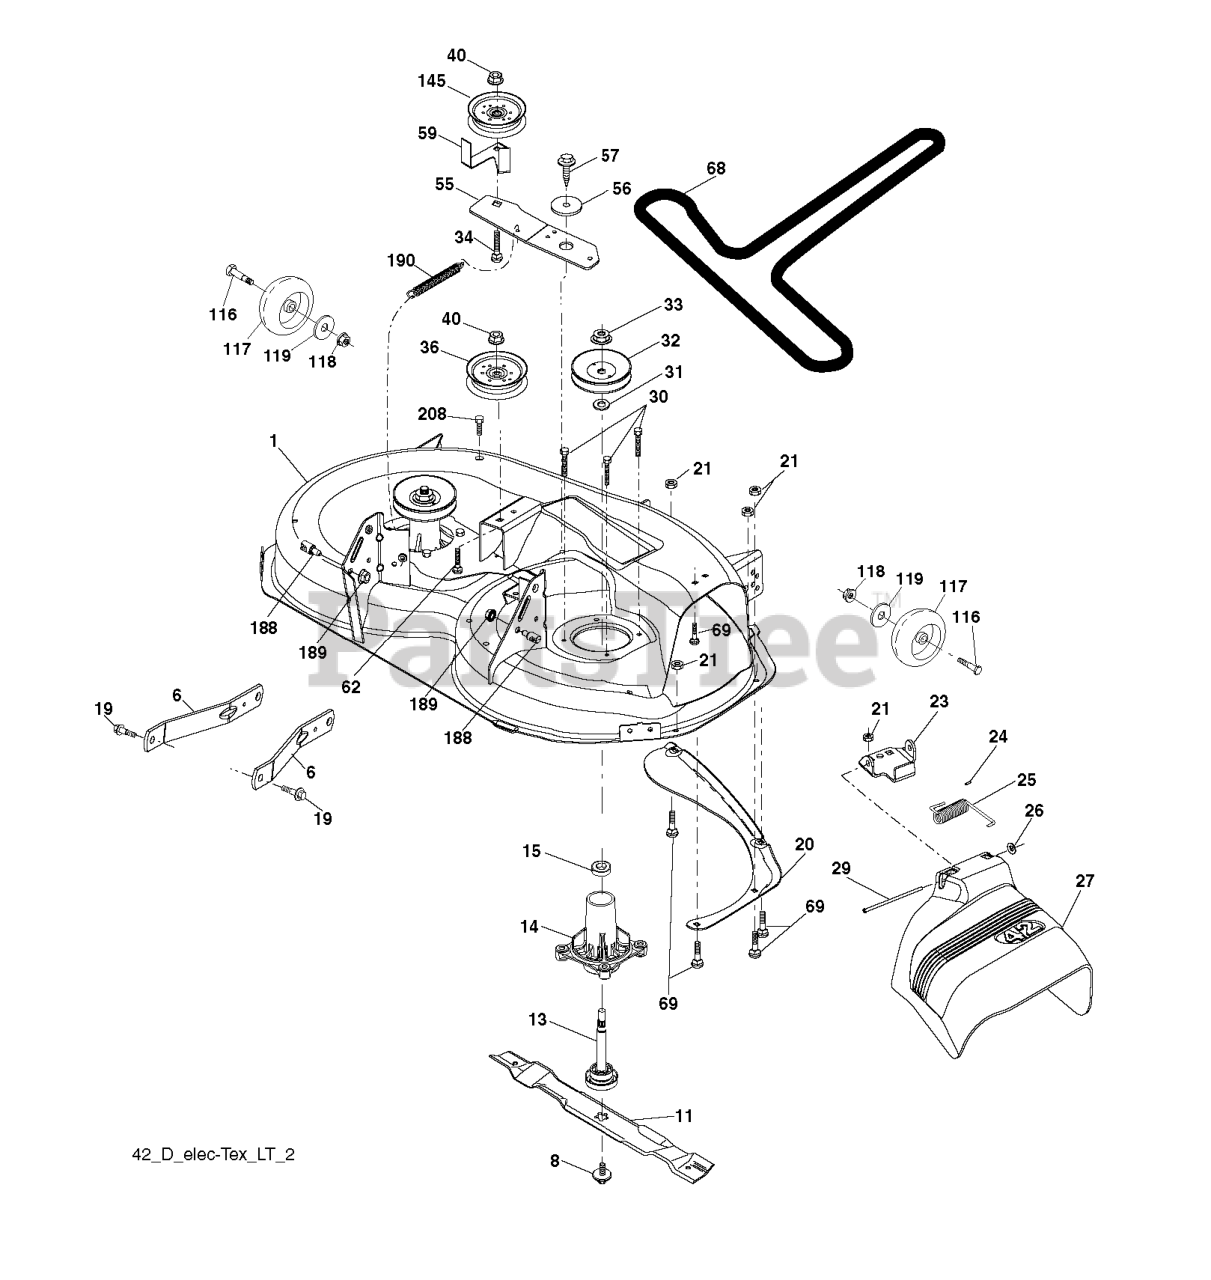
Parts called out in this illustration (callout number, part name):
2	DRAWBAR
3	SCREW 3/8-16X3/4
6	PLATE
8	CLIP,INSULATOR
9	DASH, PLASTIC
10	BOLT D
11	PANEL DASH LH
13	PANEL DASH RH
17	HOOD
25	WASHER
26	NUT
28	GRILLE.STEALTH P/L.YTGT.GREY
29	LIGHTBOX.ASM.STV.DL.INC.HUSQ
31	BRACKET SUPPORT FENDER
33	FOOTREST PNT LH
34	FOOTREST PNT RH
37	Screw 5/16-18 x 1/2 Hex, Self Tapping 5/16-18 x 1/2
38	BRACKET ASM PIVOT MOWER REAR
64	DASH.LOWER.YT.2003
69	SCREW.HI-LO.CONSOLE
89	COVER.BATTERY.CRD.GREY
145	ROD PIVOT CHASSIS/HOOD
161	EXTRUSION BUMPER (3 2) (2 2)
162	BRACKET
163	BRACKET EXTEN CHASSIS RH CRD
165	RP.COVER.BATTERY.CRD.GREY
166	SCREW
172	WASHER
175	DOOR TRAP
179	ROD PIVOT FBI
184	BRACKET.ACTUATOR.BAGGER.SRD
186	LATCH ASSY
187	WELDNUT
189	LOCKWASHER #10
190	SCREW
207	SCREW, 5/16-18 X 1/2
209	SCREW, 3/8-16X3/4
213	SKIRT GRILLE LH
214	SKIRT GRILLE RH
256	COVER FENDER CRD
258	LENS RH
259	LENS LH
265	SEALING
266	SEALING
